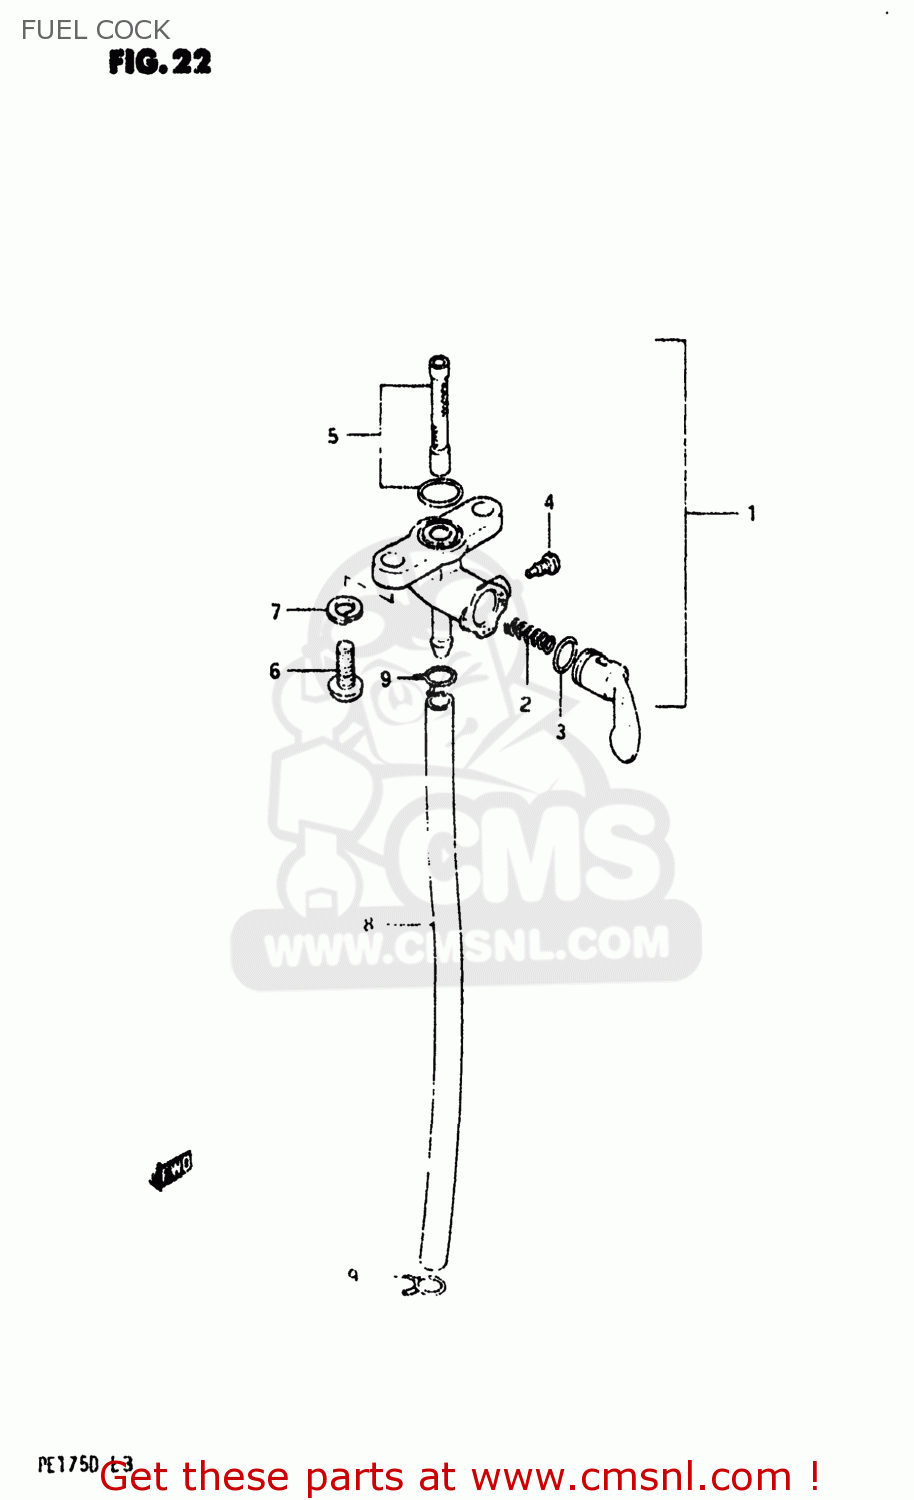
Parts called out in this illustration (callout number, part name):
1	COCK ASSEMBLY,FUEL
2	SPRING,FUEL COCK VALUE
3	O RING,LEVER
4	SCREW
5	FILTER SET FUEL
6	SCREW
7	LOCK WASHER
8	HOSE
9	CLAMP
